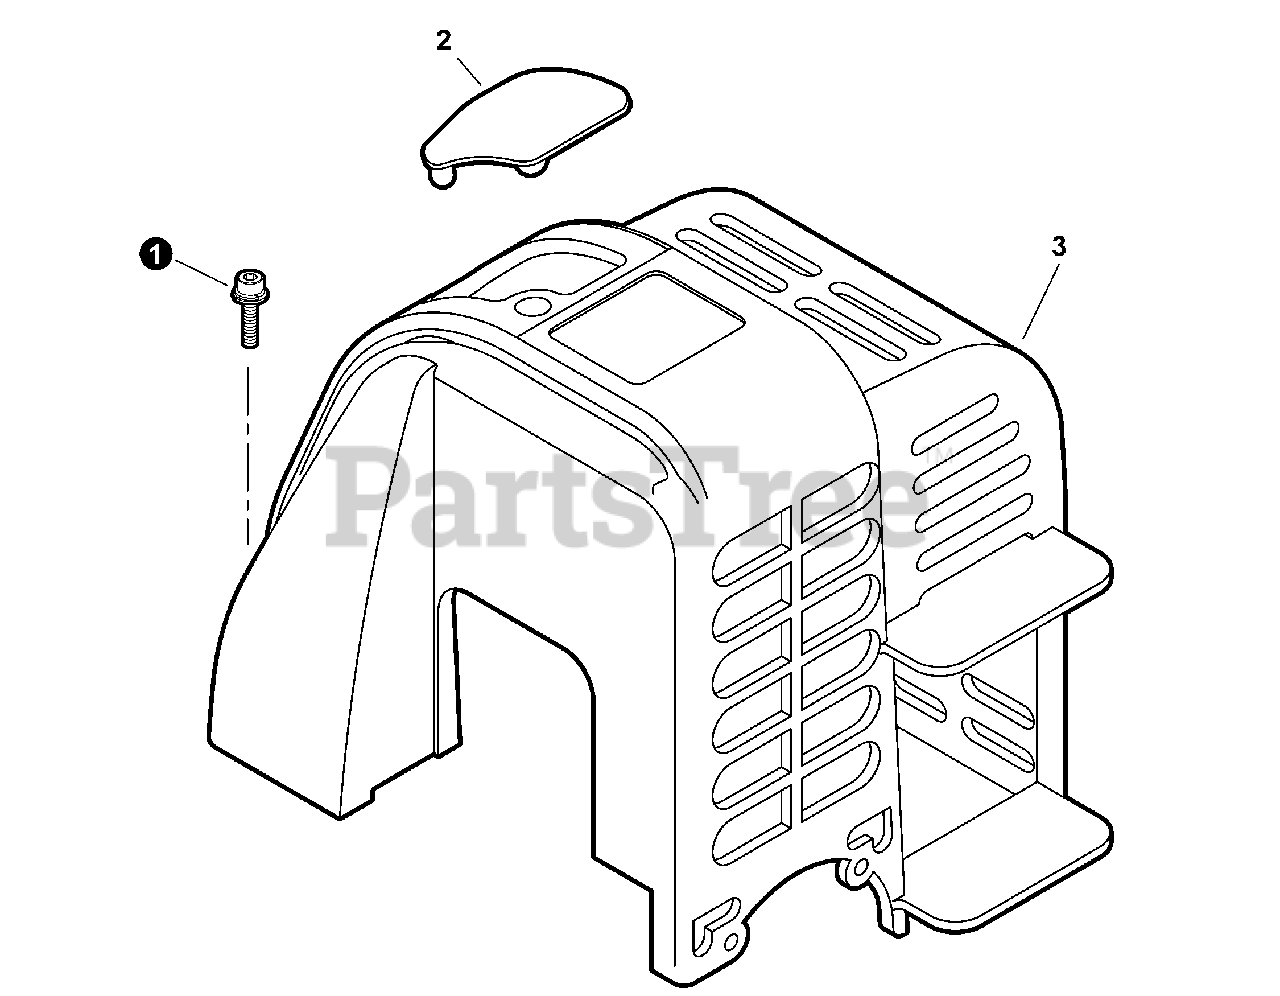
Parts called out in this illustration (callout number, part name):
1	BOLT M4×16
2	COVER, SPARK PLUG
3	COVER, ENGINE
